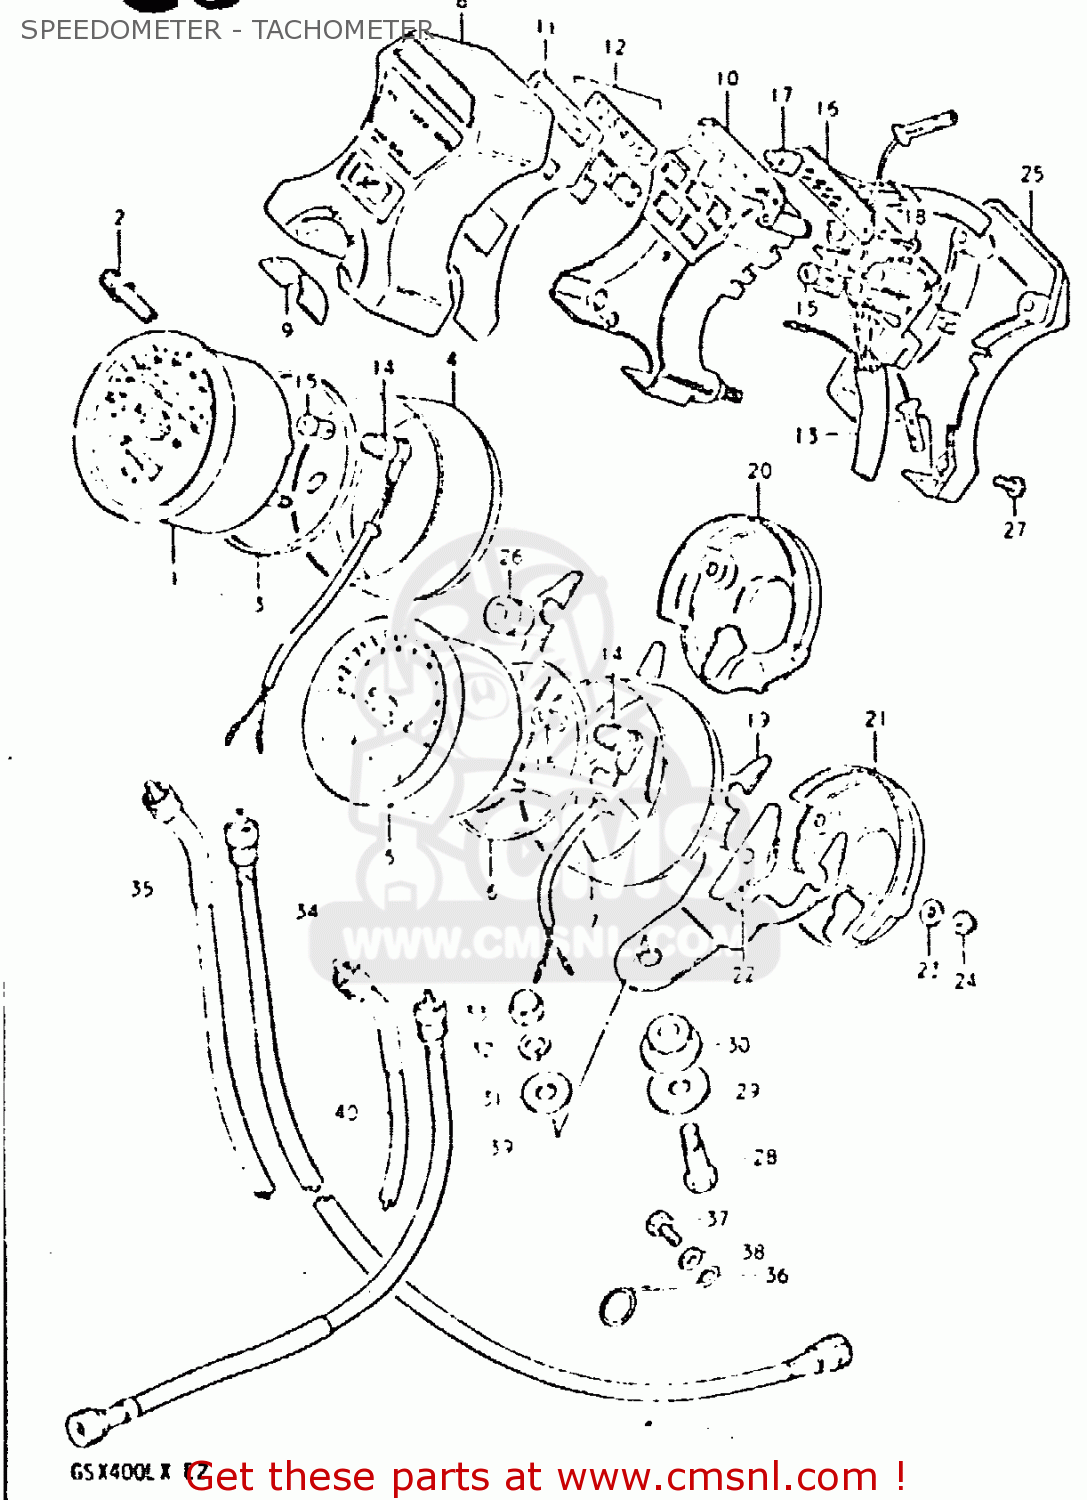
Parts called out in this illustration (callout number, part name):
1	SPEEDOMETER ASSEMBLY
2	KNOB
3	CUSHION
4	COVER,SPEEDOMETER
5	TACH0METER
6	CUSHION
7	COVER,TACHOMETER
8	CASE,PILOT BOX,OUTER
9	SEAL,IGNITION SWITCH
10	CASE, PILOT BOX INNER
11	PLATE,PILOT BOX
12	LENS SET,PILOT
13	SOCKET
14	SOCKET,METER
15	BULB(12V3.4W,STANLEY,A72A)
16	INDICATOR ASSEMBLY,GEAR POSITION
17	BULB(14V1.12W)
18	SCREW
19	BRACKET,COMBINATION METER
20	ORNAMENT,SPEEDOMETER
21	COVER,TACHOMETER
22	CUSHION,METER
23	WASHER
24	NUT
25	COVER,PILOT BOX,UNDER
26	CUSHION,PILOT BOX
27	SCREW,PILOT BOX
28	BOLT
29	WASHER
30	CUSHION,METER
31	WASHER(8.5X23X1.2)
32	LOCK WASHER
33	NUT
34	CABLE ASSEMBLY,SPEEDOMETER
35	CABLE ASSEMBLY,SPEEDOMETER
36	GUIDE,SPEEDOMETER CABLE
37	BOLT, UPPER
38	WASHER
39	CABLE ASSEMBLY,TACHOMETER
40	CABLE, TACHOMETER
